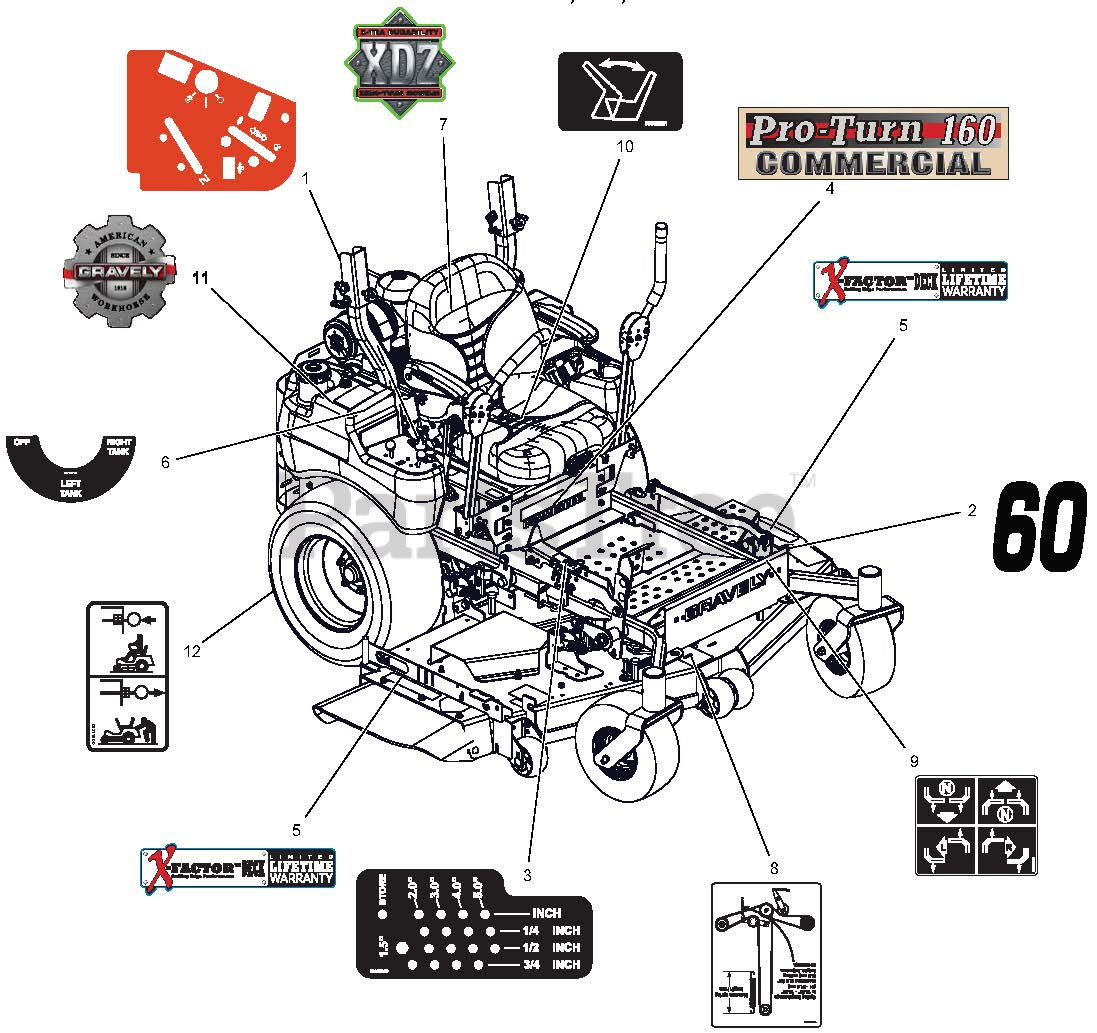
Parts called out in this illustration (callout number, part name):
1	PANEL, PT100 CONTROL
2	DECAL, 60"
3	DECAL, HEIGHT OF CUT
4	DECAL, PRO-TURN 160
5	DECAL, X-FACTOR DECK
6	DECAL, FUEL VALVE
7	DECAL, XDZ
8	DECAL, BELT DIAGRAM 60"
9	DECAL, INSTRUCTIONAL - STEERING
10	DECAL, SEAT RELEASE
11	DECAL, GRAVELY HERITAGE-LARGE
12	DECAL, TRANSMISSION DISCONNECT
